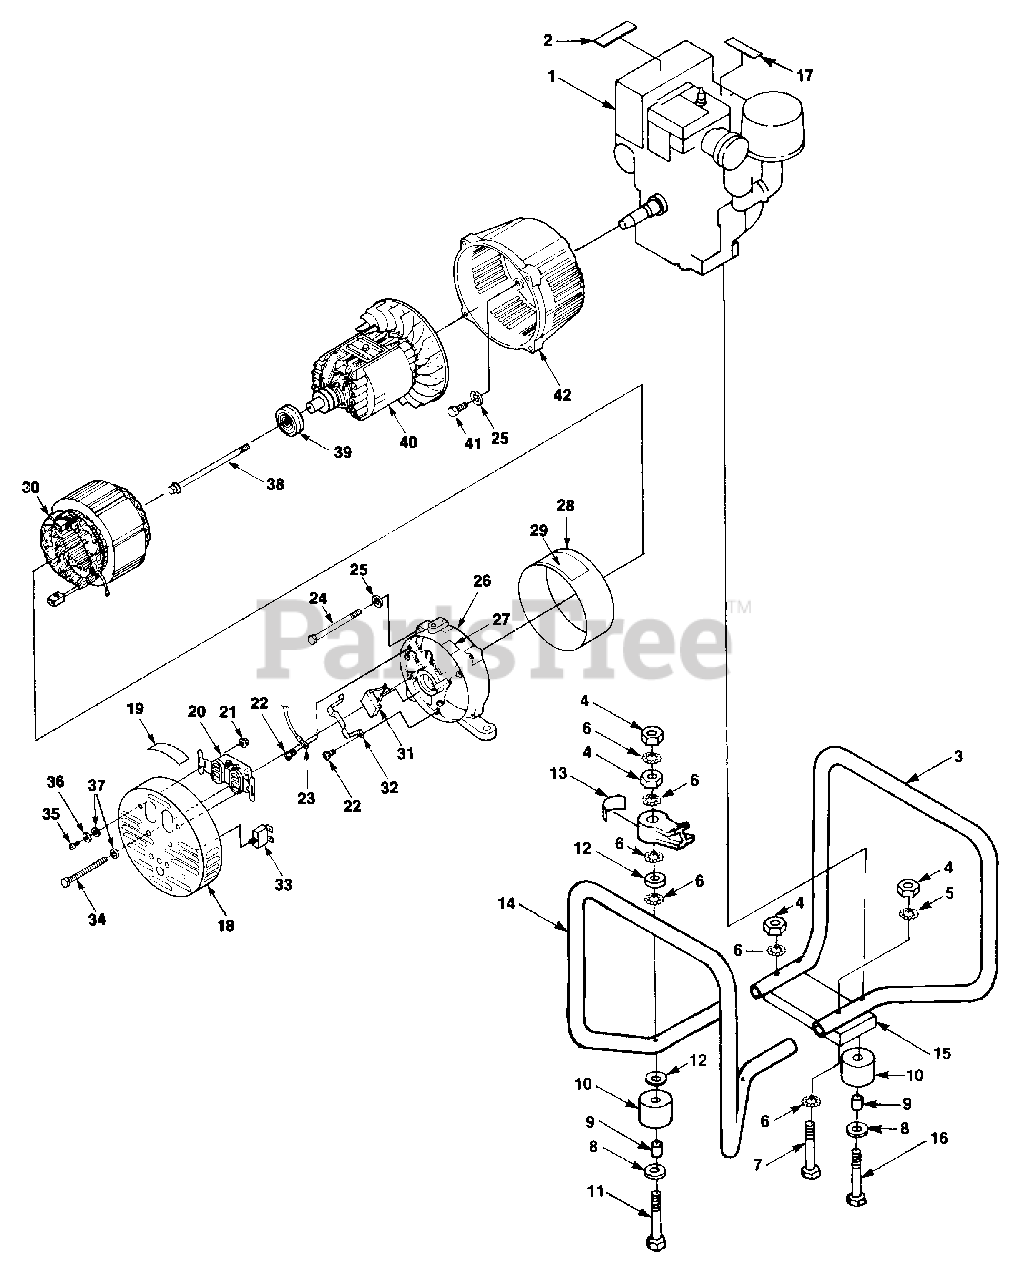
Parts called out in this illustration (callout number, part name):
1	ENGINE
2	DECAL- Caution
3	MEMBER- Frame
4	NUT- Hex (5/16-18)
5	WASHER- Lock int. (5/16")
6	WASHER- Lock ext./int.
7	BOLT- Engine (rear)
8	WASHER- Flat (5/16")
9	SPACER- Foot
11	SCREW- Cap hex. hd. (5/16-18 x 3")
12	WASHER- Flat (5/16")
13	DECAL- Ground
14	FRAME- Member
15	PLATE- Frame
16	BOLT- Engine (front)
17	DECAL- Warning
18	END COVER
19	DECAL- Warning
20	RECEPTACLE- (120V) (EH2500)
21	NUT- (120V receptacle)
22	SCREW- (m5 x 12mm)
23	LEAD- Electrical
24	BOLT- Stator
25	WASHER- Lock ext./int.
26	END BELL
28	COVER- Stator
29	DECAL- Output
31	CAPACITOR
32	HOLDER- Capacitor
33	BREAKER- Circuit (20 amp)
34	BOLT- Cover (m5)
35	SCREW- (120V receptacle)
36	WASHER- Lock
37	WASHER- Flat
38	BOLT- Rotor
39	BEARING- Ball
41	SCREW- Hex hd. (3/8-16 x 1")
